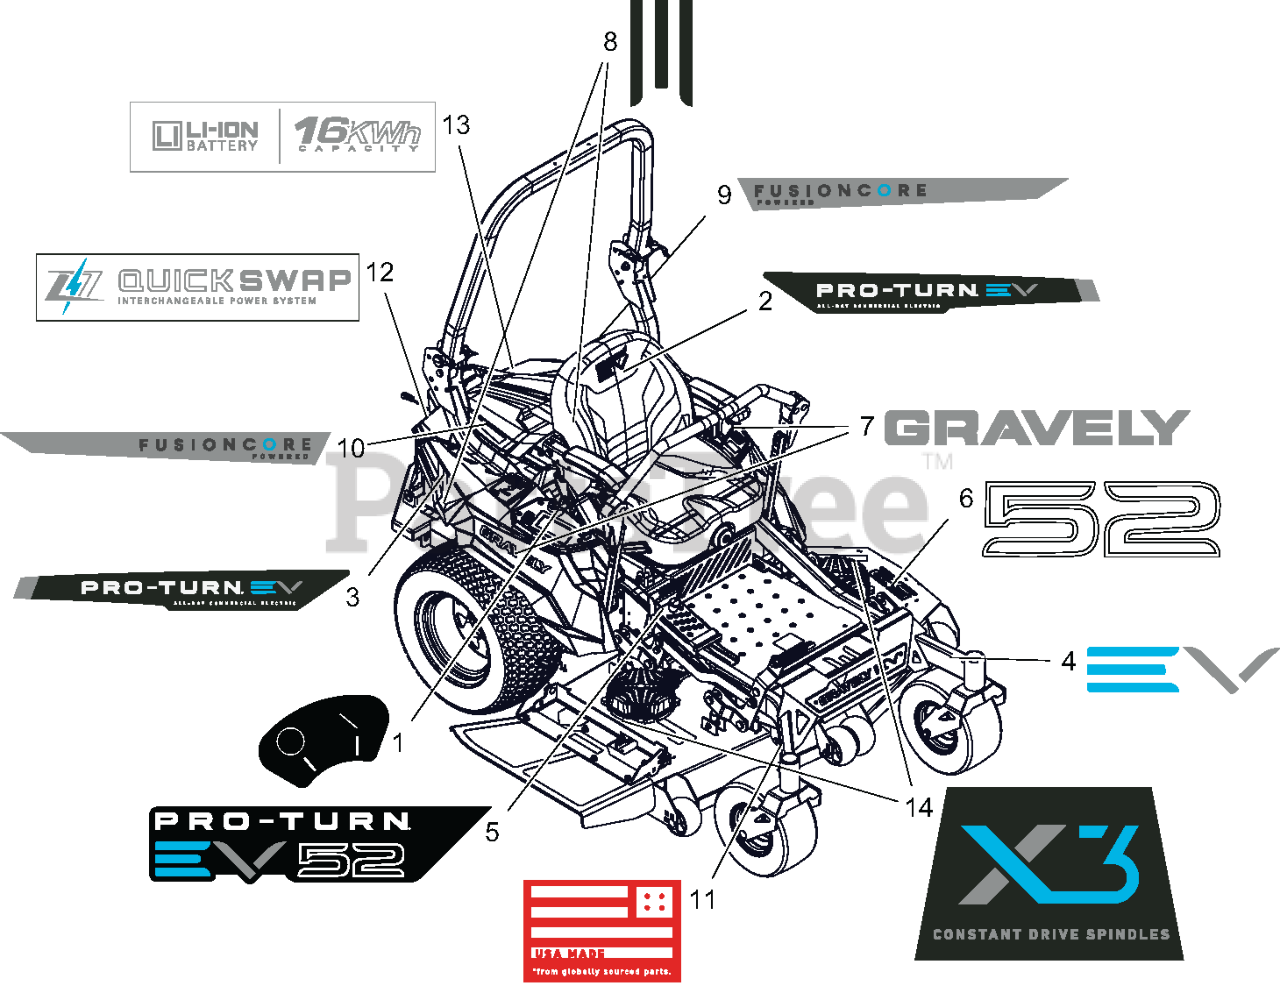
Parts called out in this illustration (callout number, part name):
1	DECAL, KEY SWITCH - 2POS
2	DECAL, FENDER - LH
3	DECAL, FENDER - RH
4	DECAL, FRONT FORK
5	DECAL, KICKPLATE - 52"
6	DECAL, DECK - 52"
7	DECAL, GRAVELY LOGO
8	DECAL, STRIPE
9	DECAL, FUSION CORE - LEFT
10	DECAL, FUSION CORE - RIGHT
11	DECAL, USA MADE
12	DECAL, QUICK SWAP -HATCH
13	DECAL, LI- ION - HATCH
14	DECAL, DECK MOTOR
